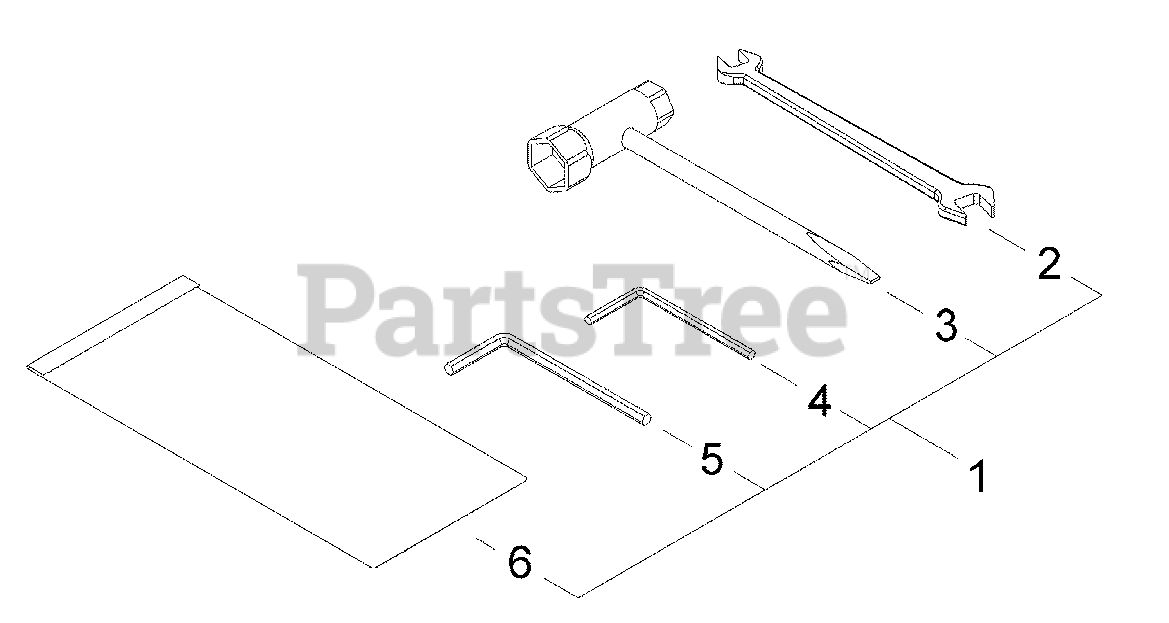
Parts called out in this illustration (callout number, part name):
1	TOOL KIT
2	SPANNER - 8X10mm
3	T-WRENCH - 13X16mm
4	HEX KEY - 3mm
5	HEX KEY - 4mm
6	BAG, TOOL
